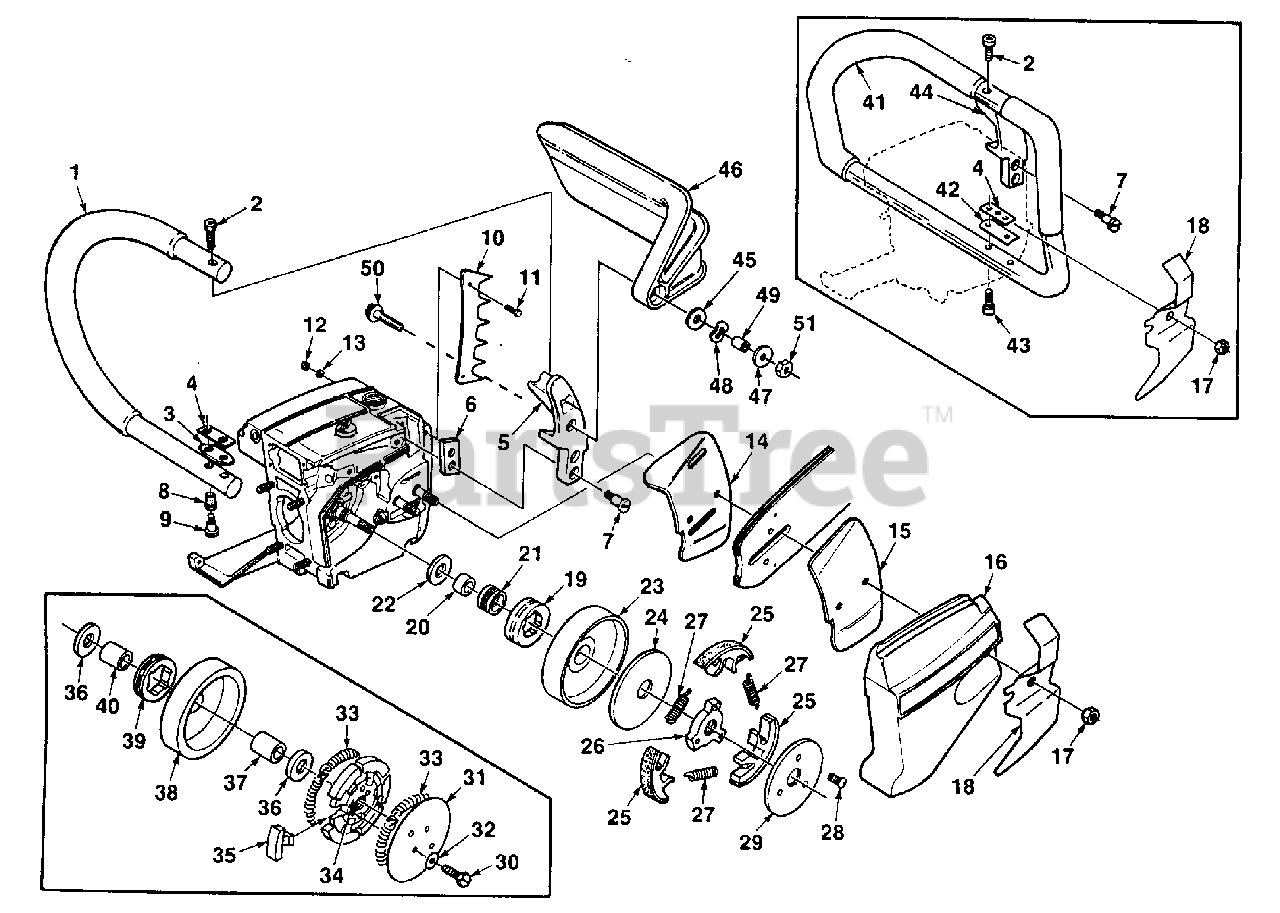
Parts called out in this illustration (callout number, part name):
1	HANDLE BAR- Flush cut (rubber cover)
2	SCREW- Fil, hd., 1/4-20 x 1
3	SPACER- Handle bar
4	PLATE- Handle bar
5	BRACKET- Handle bar (flush cut)
6	PLATE- Handle bar bracket
7	SCREW- 12-24 x 3/4
8	GROMMET- Handle bar
9	SCREW- Shoulder
10	KIT- Spiked bumper
11	SCREW- Hex hd., 12-24 x 3/4
12	NUT- 12-24
13	WASHER- Lock #12
14	PLATE- Guide bar (Inner)
15	PLATE- Guide bar (outer)
16	COVER- Drivecase
17	NUT- Hex 3/8-16
18	GUARD- Chain (SXL-925W)
19	SPROCKET- 7 spline 7T-3/8 pitch 3 shoe clutch (SXL-925W)
20	RACE- Inner
21	BEARING- Roller
22	WASHER- Thrust (inner) for rim sprocket only)
23	DRUM 8. HUB (SXL-925W)
24	WASHER- Thrust
25	SHOE- Clutch
26	SPIDER- Clutch
27	SPRING- Clutch
28	SCREW- Torx
29	COVER- Clutch
30	SCREW- Hex hd., 10-32 x 1/2 (opt.)
31	COVER- Clutch (opt.)
32	WASHER- Belleville
33	SPRING- Clutch (opt.)
34	SPIDER- Clutch (opt.)
35	SHOE Clutch (opt.)
36	WASHER- Thrust
37	BEARING- Roller
38	DRUM & HUB- Rim type (opt.)
39	SPROCKET- 3/8 pitch 7 tooth (opt.)
40	RACE- Inner
41	HANDLE BAR
43	SCREW- 1 4-20 x 1.125
44	BRACKET- Handle bar
45	WASHER
46	HAND GUARD
50	SCREW- Flat hd., 12-24 x 1
51	NUT- Lock
